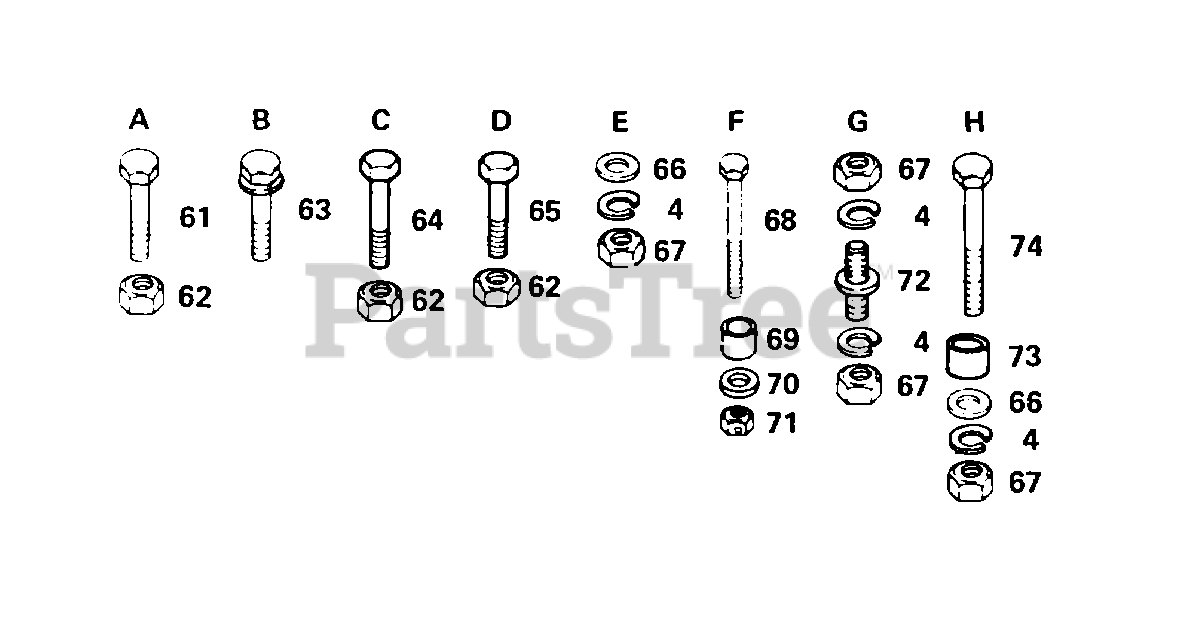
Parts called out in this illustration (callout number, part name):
4	LOCKWASHER
63	SCREW
64	BOLT
65	BOLT
66	WASHER
67	NUT.HEX.3/8-16UNC
69	BUSHING LT
70	WASHER
73	SPLIT SPACER YTV
